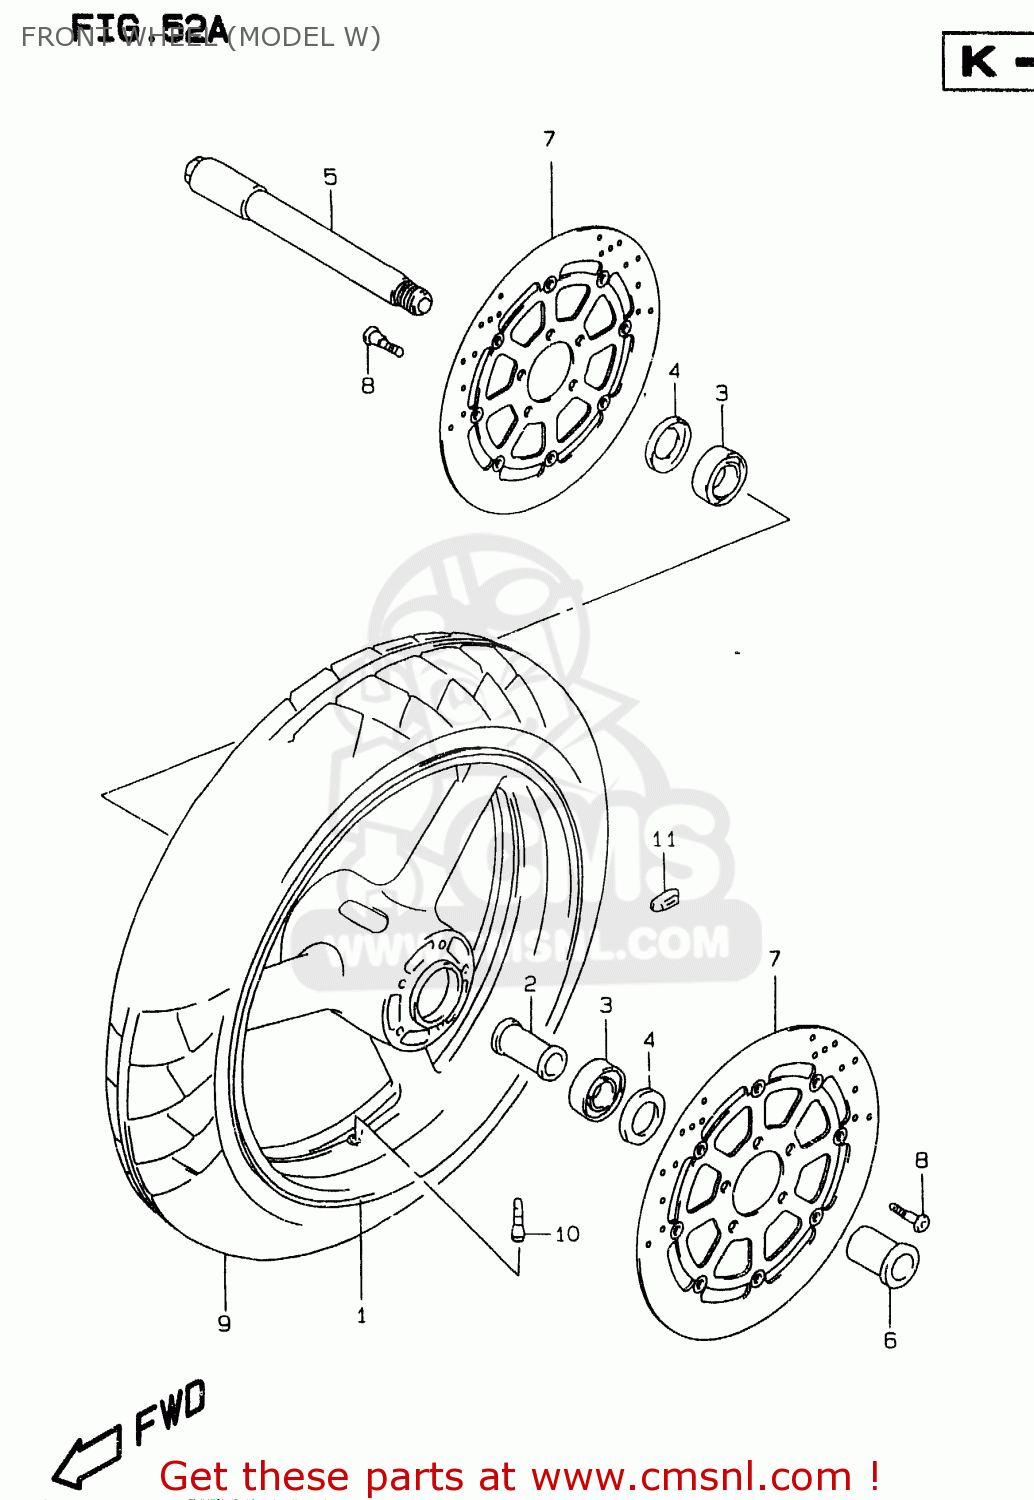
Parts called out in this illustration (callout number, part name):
1	WHEEL,FRONT (17XMT3.50)(
2	SPACER,FRONT HUB BEARING
3	BEARING(25X52X15)
4	SEAL,OIL(32X52X7)
5	AXLE,FR
6	NUT,FR AXLE
7	DISC,FR BRAKE
8	BOLT 8X33
9	TIRE,FRONT 120/70 ZR17
10	VALVE ASSEMBLY,WHEEL,TR412
11	BALANCER,WHEEL (10G)
